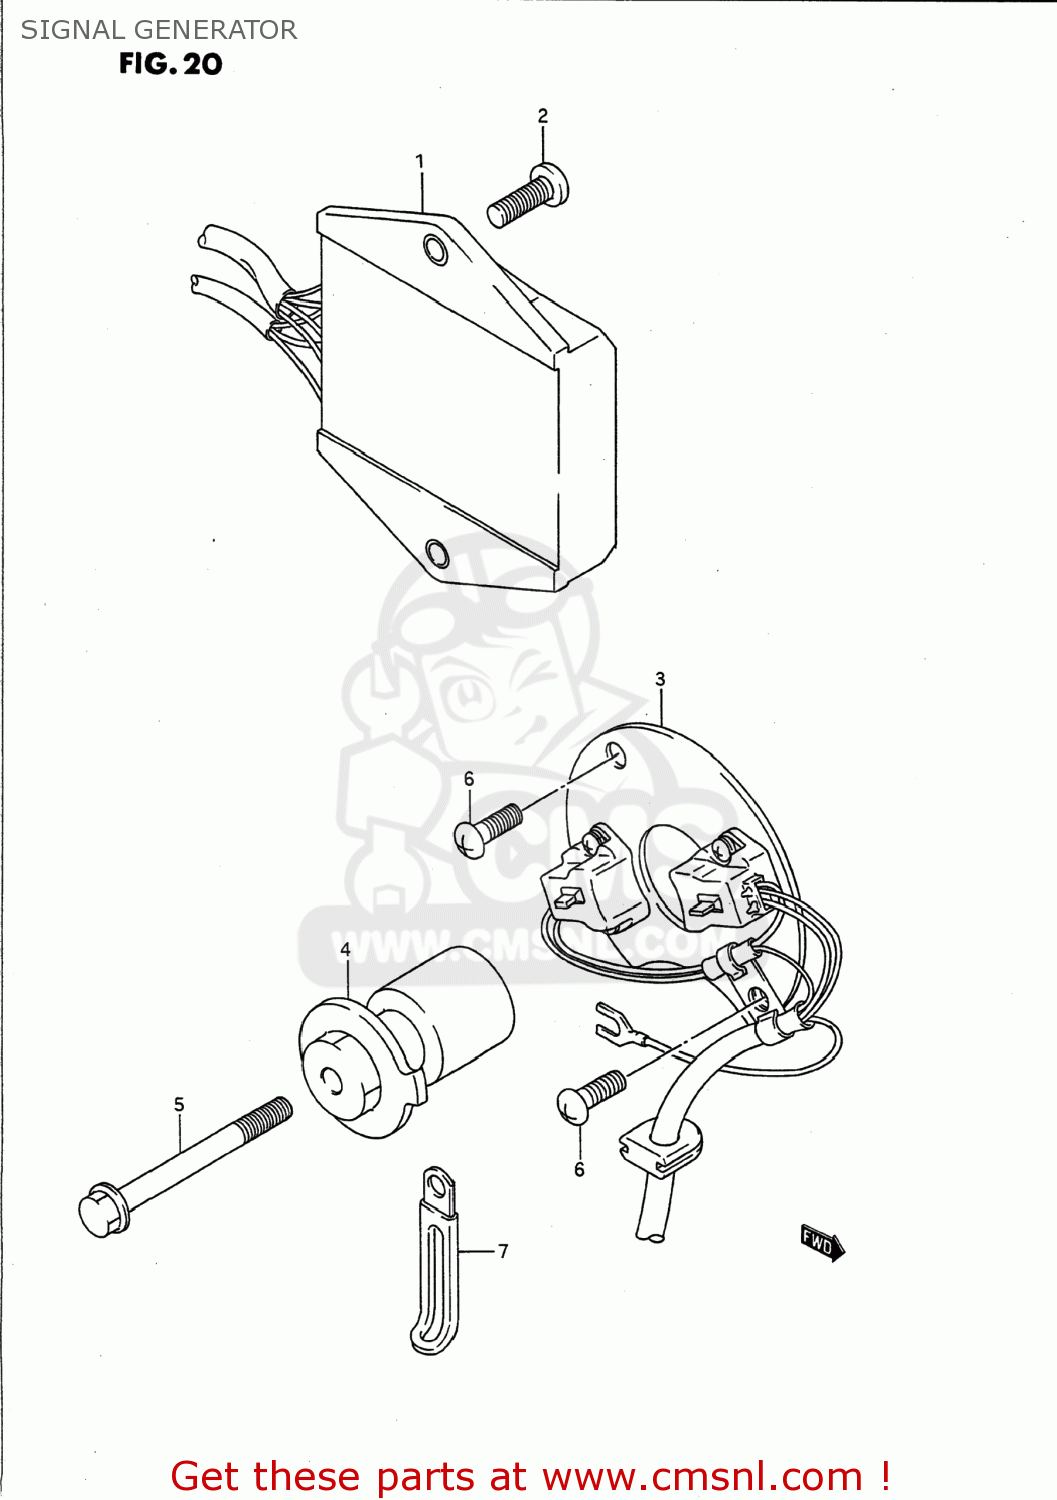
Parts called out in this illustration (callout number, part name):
1	IGNITER ASSEMBLY
2	SCREW
3	SIGNAL GENERATOR ASSY
4	ROTOR,SIGNAL
5	BOLT
6	SCREW
7	CLAMP
